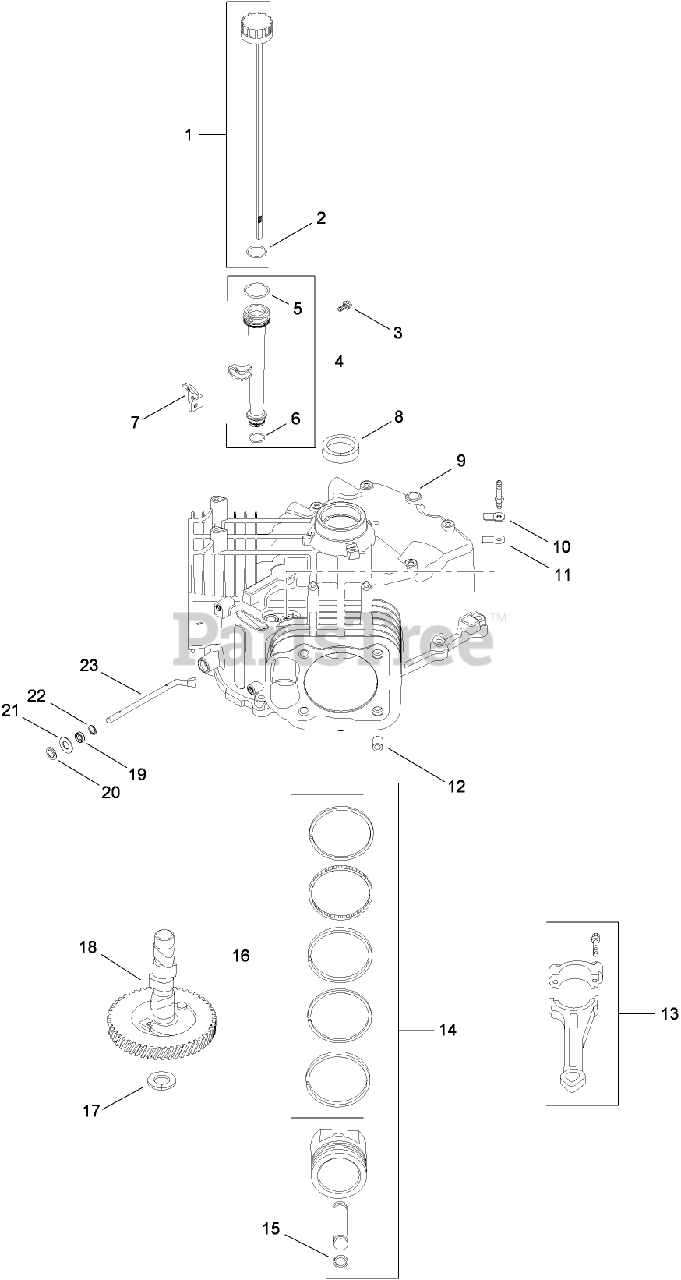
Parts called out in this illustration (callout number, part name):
1	DIPSTICK ASM (INCLUDES 2)
2	O-RING
3	SCREW-FLG, THD FRM (M5X0.8X13)
4	OIL FILL TUBE KIT
5	O-RING
6	O-RING
7	BRACKET-TUBE, OIL FILL
8	SEAL-OIL
9	Loose Parts Package
10	RETAINER-REED, BREATHER
11	REED-BREATHER
12	PIN-LOCATING
13	ROD-CONNECTING (STD)
14	PISTON KIT W/RING SET (STD) (INCLUDES 15-16)
14	PISTON KIT W/RING SET (.25)
14	PISTON W/RING SET (.08)
15	RETAINER-PIN, PISTON
16	RING SET (STD AND .08)
16	Ring Set (.25)
17	SHIM-CAMSHAFT (WHITE .028)
17	SHIM-CAMSHAFT (BLUE .03)
17	SHIM-CAMSHAFT (RED .032)
17	SHIM-CAMSHAFT (YELLOW .034)
17	SHIM-CAMSHAFT (GREEN .036)
17	SHIM-CAMSHAFT (GRAY .038)
17	SHIM-CAMSHAFT (BLACK .04)
18	CAMSHAFT KIT (INCLUDES 25 357 14-S)
19	SEAL-CROSS SHAFT, GOVERNOR
20	RETAINER-RING
21	WASHER-FLAT (9MM)
22	WASHER-FLAT (11/32)
23	SHAFT-CROSS, GOVERNOR
24	LUBRICANT-CAMSHAFT
